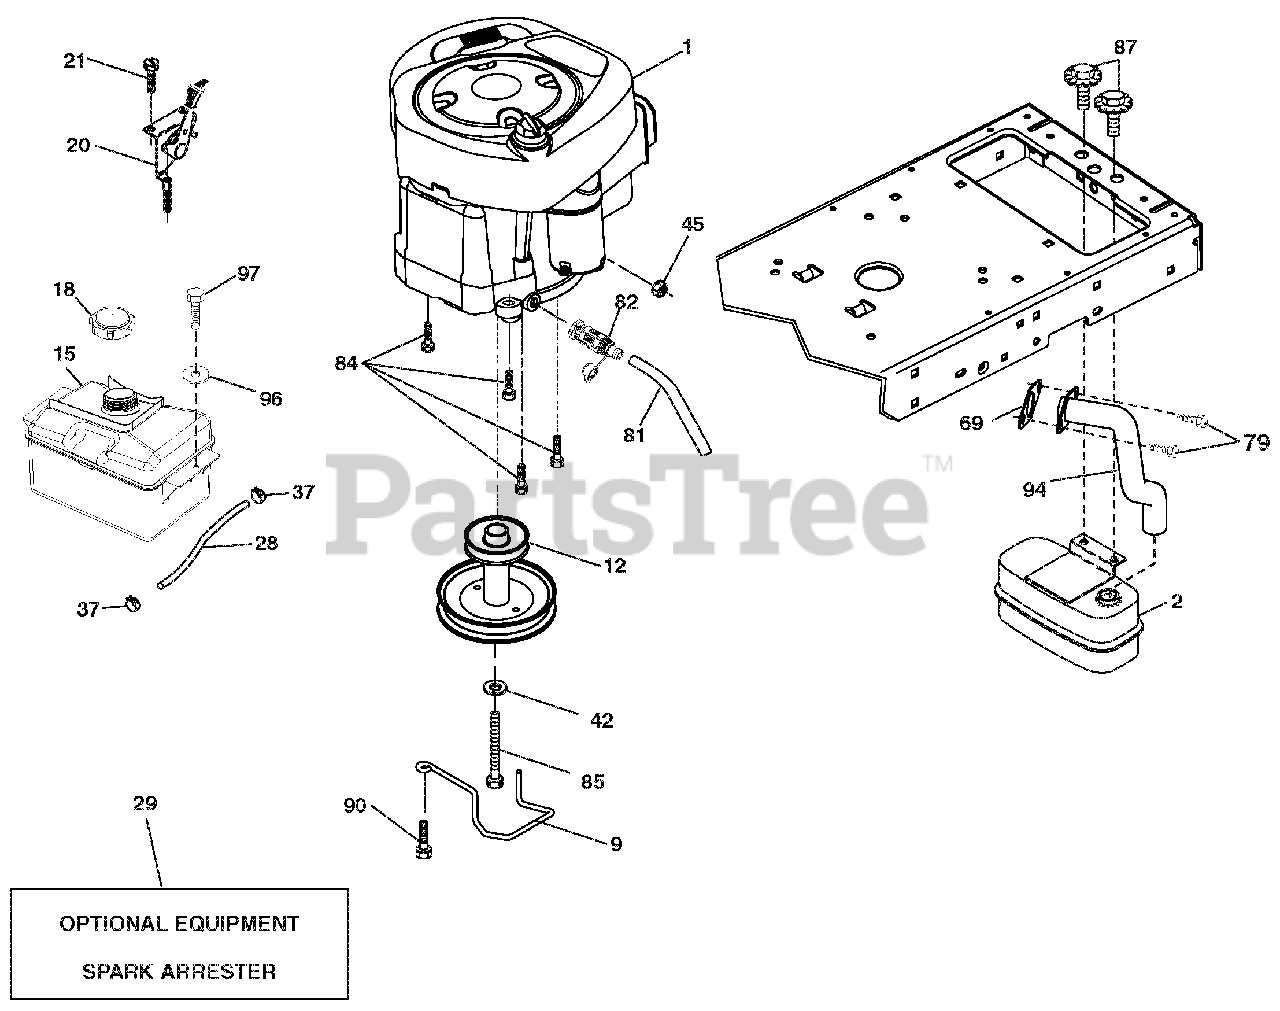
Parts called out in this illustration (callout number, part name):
1	ENGINE BRIGGS MODEL NO. 331777-2372-G5(438212) (ORDER PARTS FROM ENGINE MANUFACTURER)
2	MUFFLER.SINGLE.CYL.KOHL.COURAG
9	KEEPER.BELT.ENGINE.4.25"NSTG
12	PULLEY ENGINE
15	TANK FUEL
18	CAP FUEL
20	CONTROL THROTTLE/CHOKE
28	LINE.FUEL.22"FRONT.EMIS.CA.LP
29	KIT.SPARK ARRESTOR(392390 B&S)
37	CLAMP.HOSE.BLK.
42	WASHER.LOCK.HVY HLCL.SPR.7/16
45	Nut, Keps Hex 1/4-20 unc
69	Gasket Eng 1 313 Id Tin Plated
79	SCREW.SOCKET HD.5/16-18 X .75
81	TUBE.DRAIN.OIL.EASY
82	VALVE OIL DRAIN
84	Screw 3/8-16 x <
85	BOLT.HEX.7/16-20X4XGR5-1.5THR.
87	BOLT.5/16-18UNCX3/4 W/SEMS.BLK
90	SCREW.3/8-16X1.SMGML.TAP/R.BLK
94	EXHAUST TUBE
96	WASHER.9/32 X 7/8 X 16GA.
97	SCREW.HEXWSH.THDROL.1/4-20X3/4
